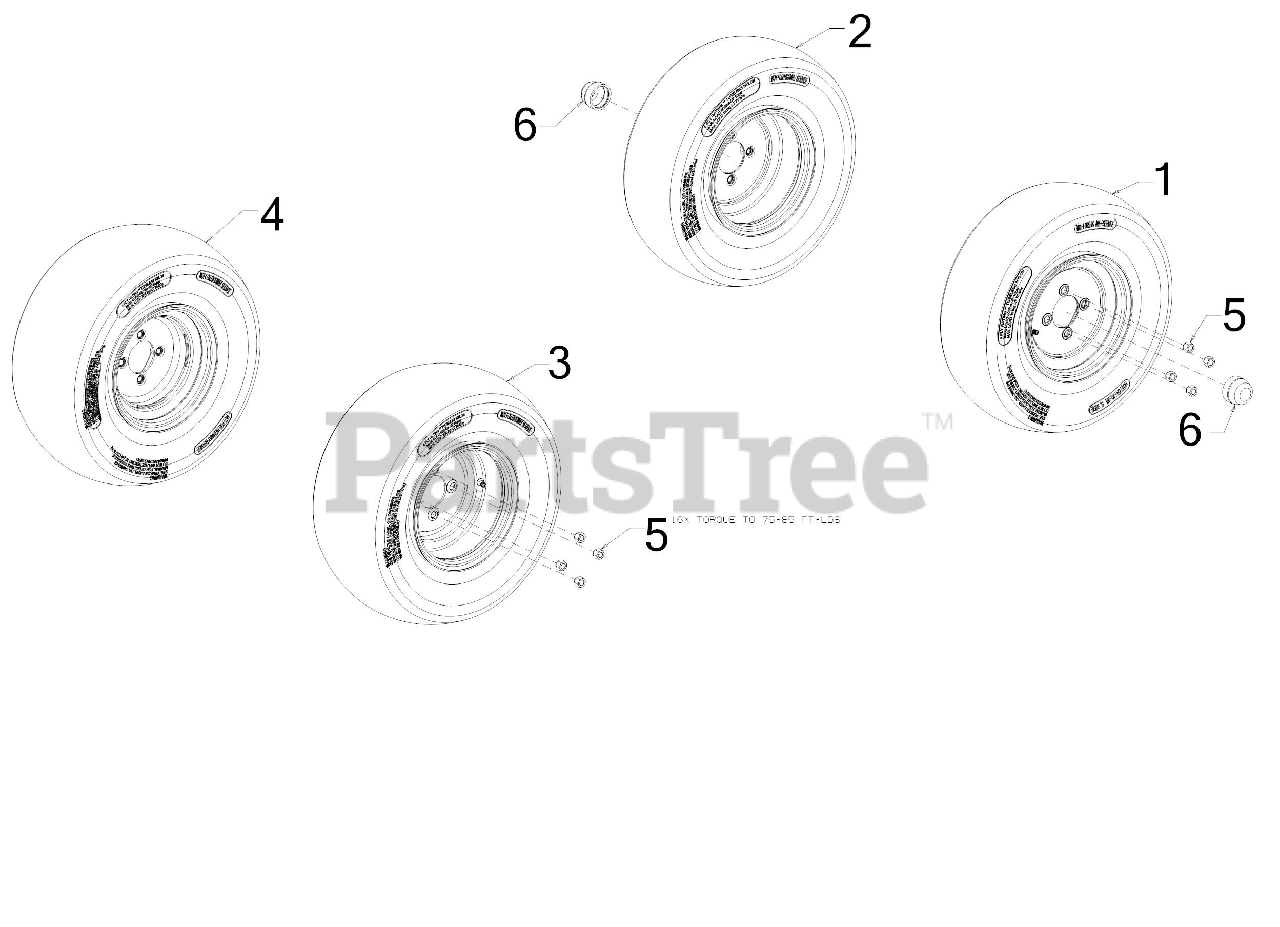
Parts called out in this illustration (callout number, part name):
1	WHEEL ASSEMBLY 21 X 7-10
2	WHEEL ASSEMBLY 21 X 7-10
3	WHEEL ASSEMBLY 22 X 9-10
4	WHEEL ASSEMBLY 22 X 9-10
